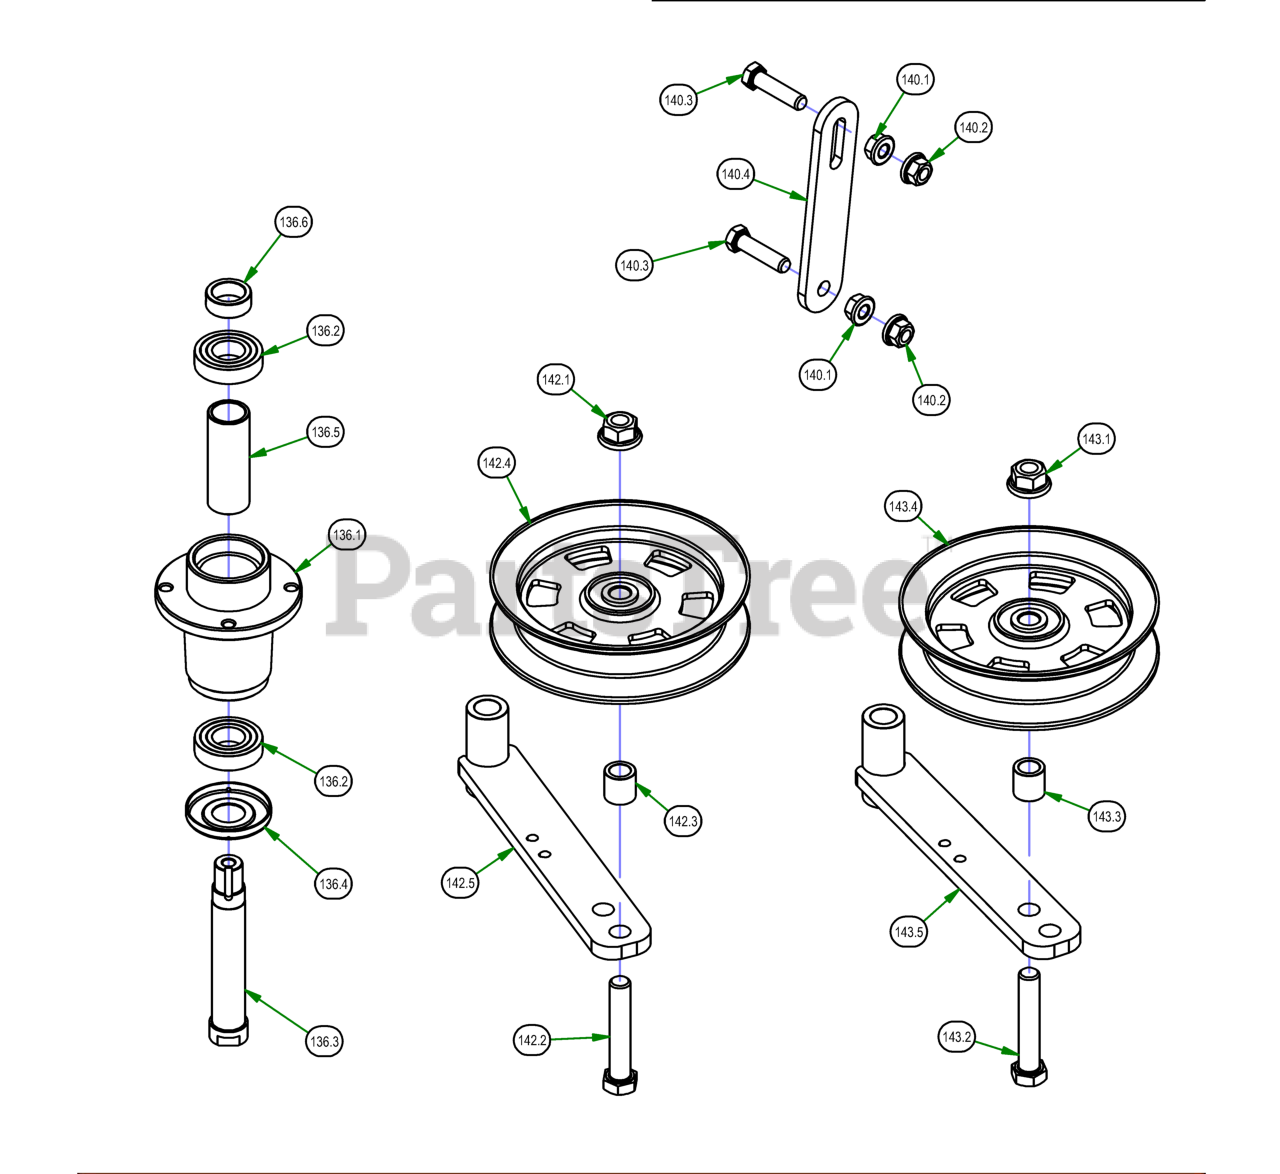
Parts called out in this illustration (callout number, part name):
136	Spindle Assembly
136.1	Spindle Housing
136.2	Bearing - 6206
136.3	Spindle Shaft
136.4	Spindle Dust Cap
136.5	Spindle Spacer
136.6	Locking Collar w/ 1/4"-20 Set Screw
140	Deck Hanger Assembly
140.1	3/8-16 HEX SERRATED FLANGE NUT HARD/ZINC
140.2	3/8-16 NYLON INSERT FLANGE LOCKNUT (GR.F) ZINC
140.3	3/8-16 X 1-1/2 HEX CAP SCREW (GR.5) ZINC
140.4	2017 MZ/ZT Deck Hanger
142	2017 MZ/ZT Deck Idler Assembly
142.1	1/2-13 NYLON INSERT FLANGE LOCKNUT ZINC
142.2	1/2-13 X 2-3/4 HEX CAP SCREW (GR.5) ZINC
142.3	.51 ID X .75 OD X .75 LGTH SOLID SPACER ZINC
142.4	5" Idler Pully
142.5	Deck Idler
143	2017 54"/48" Deck Idler Assembly
143.1	1/2-13 NYLON INSERT FLANGE LOCKNUT ZINC
143.2	1/2-13 X 2-3/4 HEX CAP SCREW (GR.5) ZINC
143.3	.51 ID X .75 OD X .75 LGTH SOLID SPACER ZINC
143.4	5" Idler Pully
143.5	Deck Idler
